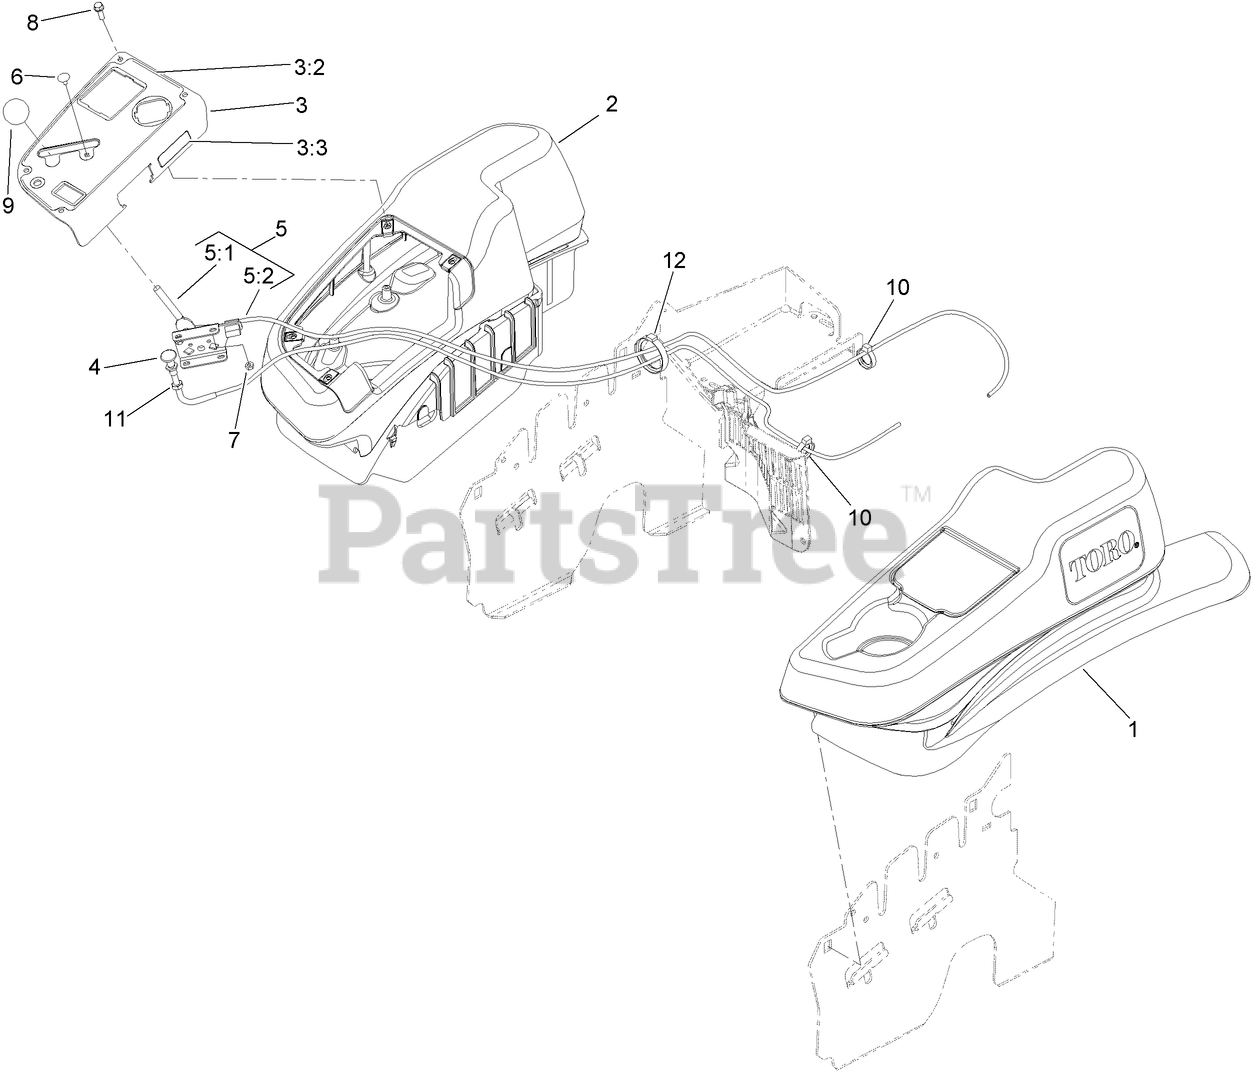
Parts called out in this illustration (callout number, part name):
1	LH NARROW FENDER/CONSOLE ASM
2	RH NARROW FENDER/CONSOLE ASM
3	CONTROL PANEL ASM
3:2	DECAL-CONTROL PANEL
3:3	DECAL-FUSES
4	CONTROL-CHOKE
5	THROTTLE CONTROL ASM
5:1	LEVER-THROTTLE
5:2	CABLE-THROTTLE
6	BOLT-CARR
7	NUT-LOCK, NI
8	SCREW-HWH
9	KNOB-BALL
10	CLAMP-HOSE
11	NUT-HJ
12	CLAMP-HARNESS
